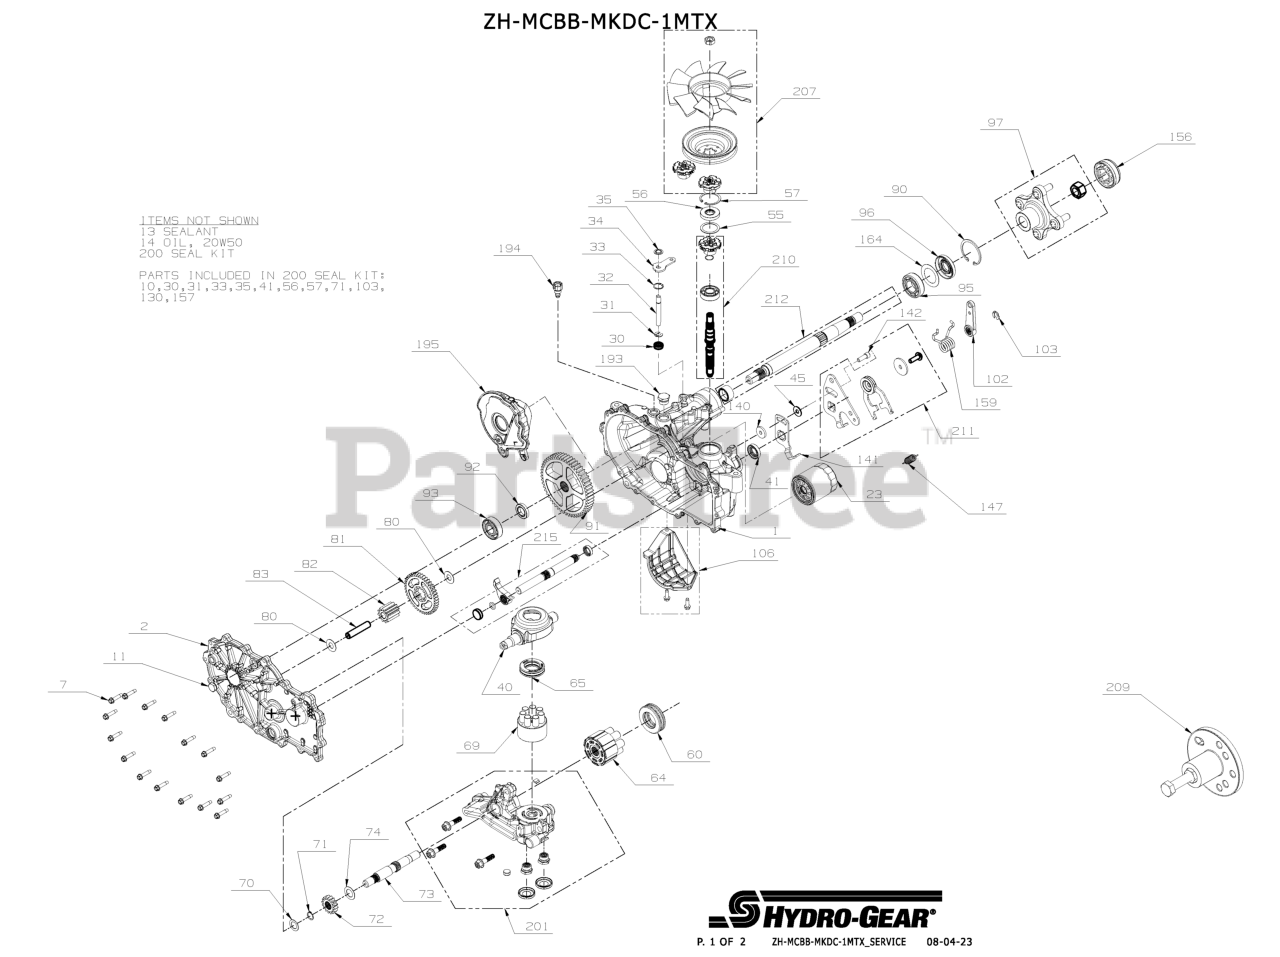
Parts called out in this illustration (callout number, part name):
1	KIT, HOUSING, MAIN, LH, CNTL
2	KIT, SIDE COVER, LH
7	SCREW,HEX WASHER 1/4-20X1.125
11	PLUG EXT HEX VENT 9/16 18
13	SEALANT TUBE 10.1OZ.
14	FLUID, HYDRO 15W50 QT
14	FLUID, HYDRO 20W50 QT
23	FILTER, HYDRO-GEAR 2800 TRANS
30	Seal, lip .375 x 375 x 325
31	RING. RETAINING
32	ROD, BYPASS
33	RING, RET .750
34	ARM, BYPASS
35	RING, RTNG .
40	TRUNNION, SWASHPLATE
41	SEAL, LIP 18X32X7
55	WASHER 1.23X1.56X.04
56	SEAL, LIP 17 X 40 X 7 HNBR
57	RING, RET 1.56 INT
60	HG THRUST BEARING (51462)
64	HG 16CC CYLINDER BLOCK (71579)
65	BEARING. THRUST 30 X 52 X 13
69	ASSY, BLOCK 7 PISTON
70	WASHER .63X1.0X.05
71	RING, RET 62 EXT
72	GEAR 16 TOOTH
73	SHAFT, MOTOR
74	WASHER .71 X 1.16 X .04
80	WASHER .5X1.0X.032
83	PIN, JACKSHAFT
90	RING, RETAINING
91	GEAR 54 TOOTH
92	SPACER
93	KIT, BEARING
95	BEARING, BALL 25.4 X 52 X 15
96	SEAL, LIP
97	KIT, HUB 4 BOLT
102	HANDLE- ACTUATING
103	CLIP,BRAKE ARM HYDROGEAR 52027
106	KIT, FILTER GUARD
141	ARM, NEUTRAL LEFT
142	SHCS 5/16-24X1 PATCH
147	SPRING, EXTENSION
156	CAP, AXLE
159	SPRING, TORSION, CW
164	WASHER, 1.355 x 2.035 x .021 FLAT
194	ASSEMBLY, FITTING 9/16-18 BREATHER
195	ASSEMBLY, TANK, EXPANSION, INTERNAL, LH
200	KIT, SEAL
201	KIT, CENTER SECTION, LH
207	KIT, FAN / PULLEY
209	HUB PULLER 5 BLT
210	KIT, INPUT SHAFT
211	RING, RTNG .
212	KIT SHAFT AXLE
215	KIT, OUTBOARD, RH ROT B / LH ROT A
